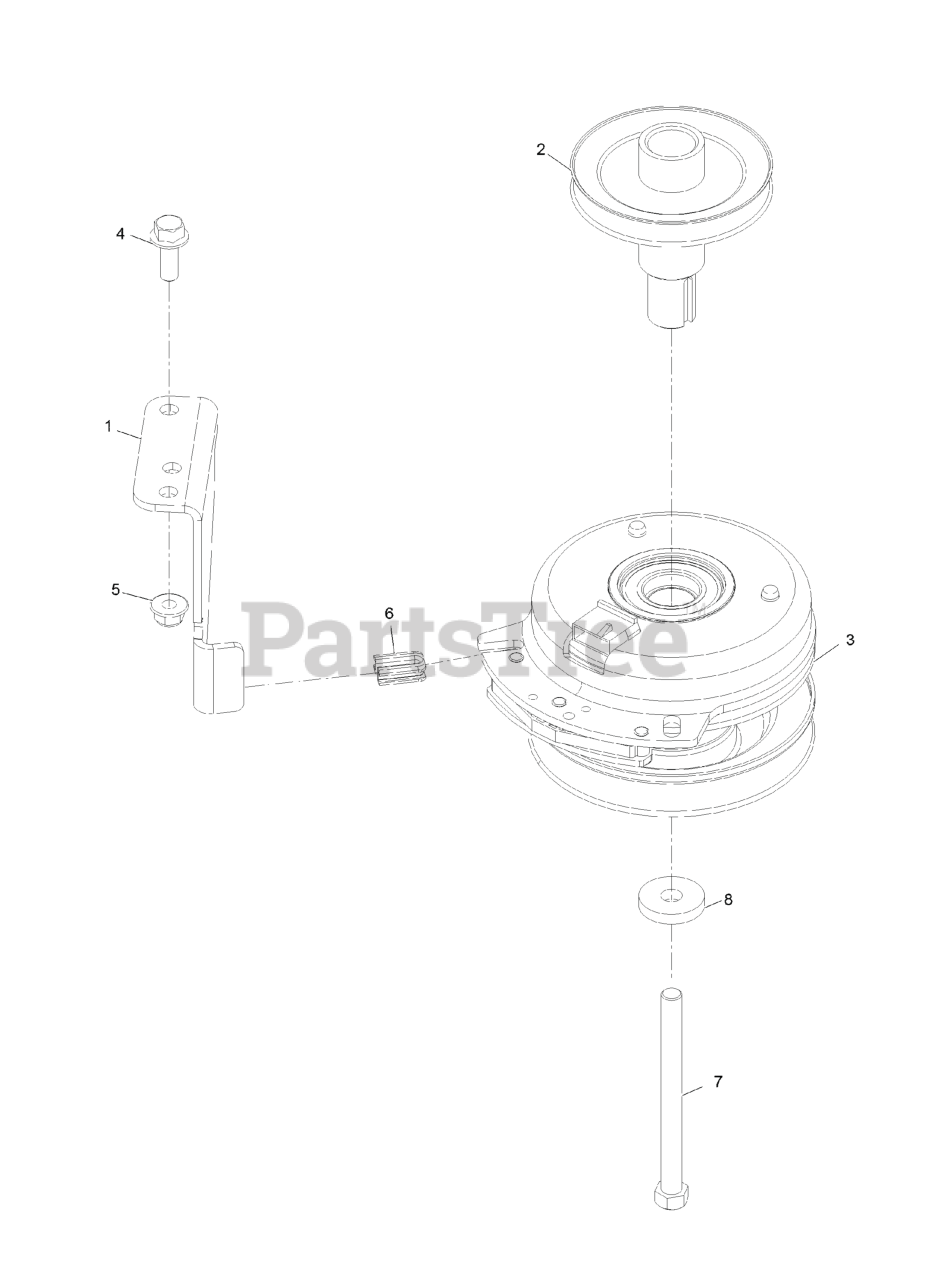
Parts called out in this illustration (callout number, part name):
1	STOP-CLUTCH (WIDE)
2	Pulley-Engine
3	CLUTCH-PTO
4	SCREW-HHF 3/8-16 X 1
5	NUT-HF, NI
6	ISOLATOR-CLUTCH
7	SCREW-HH
8	WASHER
